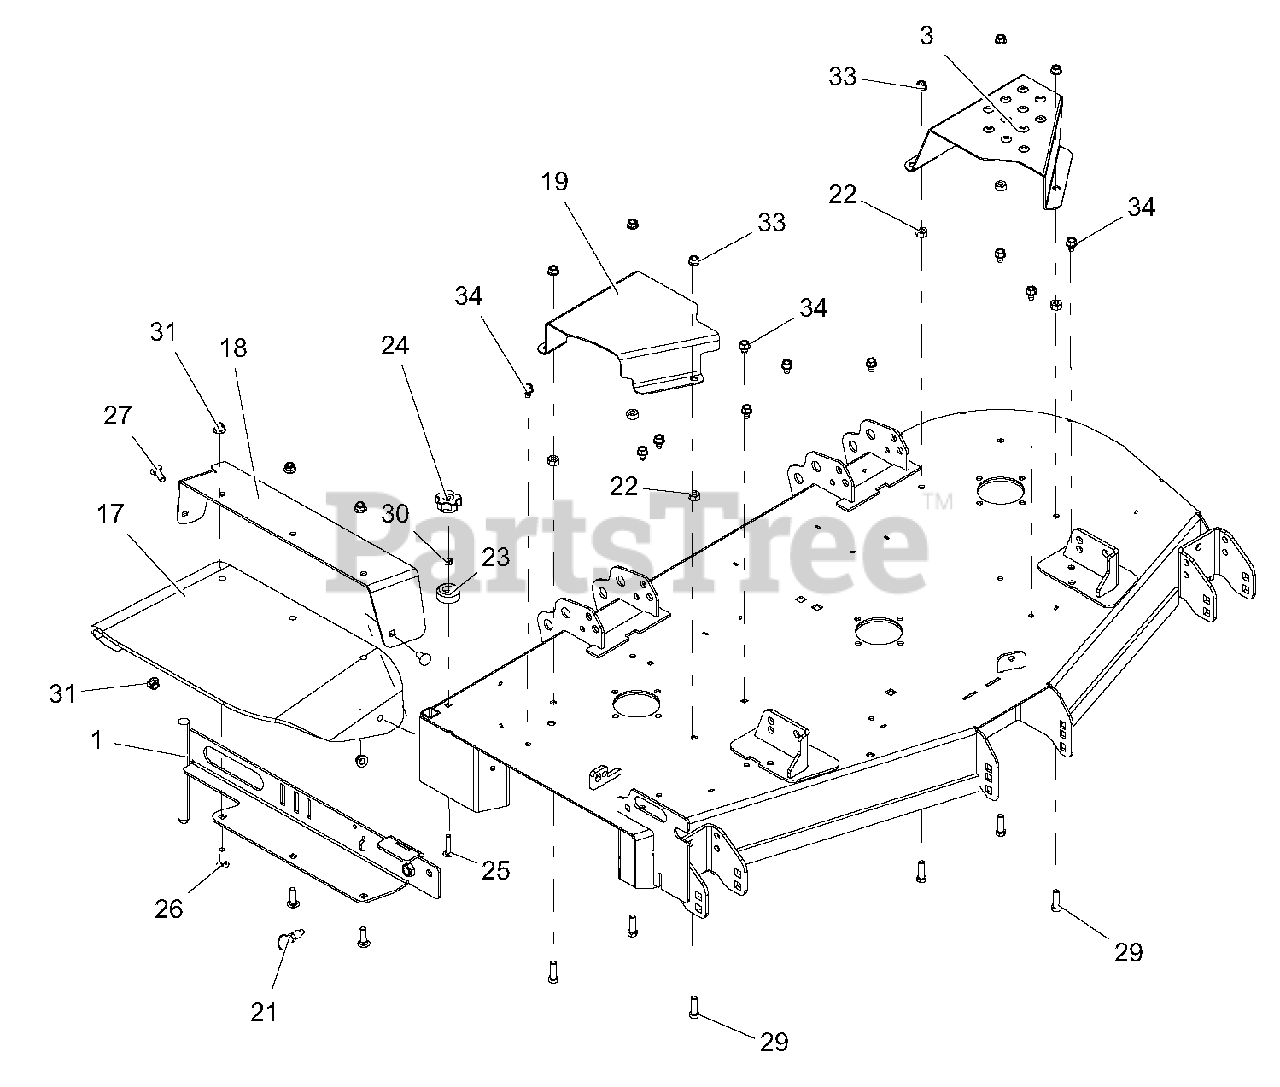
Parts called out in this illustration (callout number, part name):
1	WLDMT, 52"-60" DISCH CHUTE MTG-RED
3	GUARD, 44-52" LH DECK BELT-BLACK
17	CHUTE, RUBBER DISCHARGE
18	SUPPORT, CHUTE MOUNTING BRACKET-RED
19	GUARD, 48"-52" RH DECK BELT-BLACK
21	PULL PIN,.50-13THDX.310 PLNGR
22	NUT-HEAVY HEX .38-16 YWZC
23	BUMPER, RECESSED 1.50 X .63 W/.31 HOLE
24	KNOB, CLAMPING
25	@BLT-RDHDSQNK .31-18X1.50 G5 YWZC
26	@BLT-RDHDSQNK .38-16X1.25 G5 YWZC
27	@BLT-RDHDSQNK .38-16X1.00 G5 YWZC
29	BLT-HEX .38-16X1.25 GR5 YWZC
30	@NUT-LK-CTR .31-18 YWZC
31	NUT-LK-NYL-FLG .38-16 YWZC
33	@NUT-SPNLK-FLG .375-16 YWZC
34	SCR-TAP .38-16X.50 HWH TR YWZ
